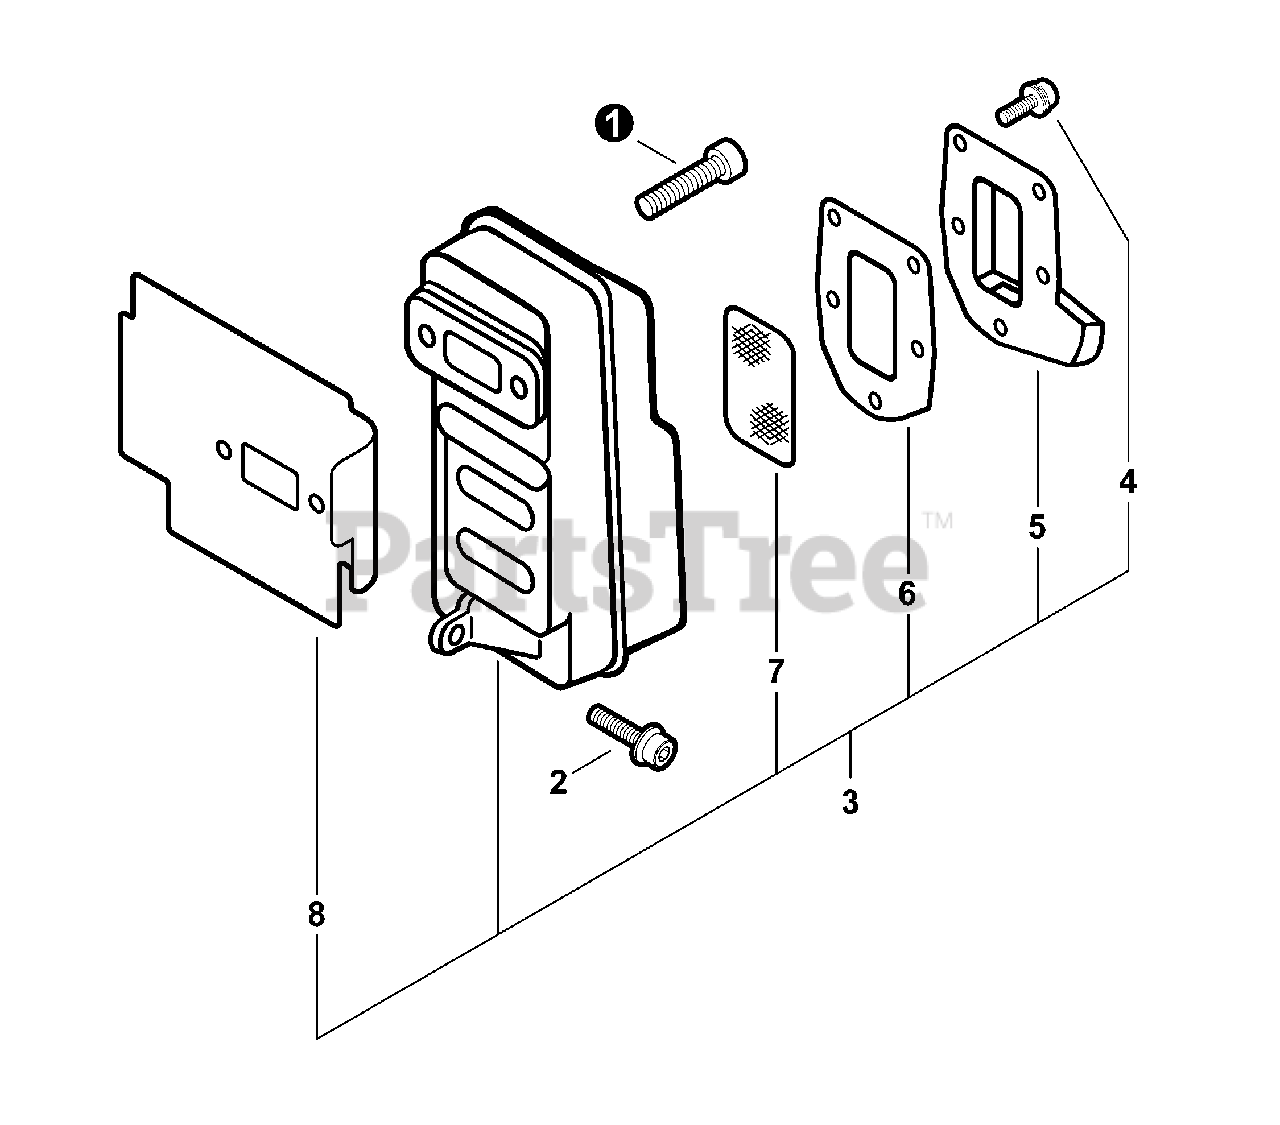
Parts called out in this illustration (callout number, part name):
1	BOLT 6×20
2	BOLT 5×16
3	MUFFLER ASSY
4	SCREW 4×10
5	GUIDE, EXHAUST
6	GASKET, EXHAUST
7	SCREEN, SPARK ARRESTER
8	HEAT SHIELD, EXHAUST
